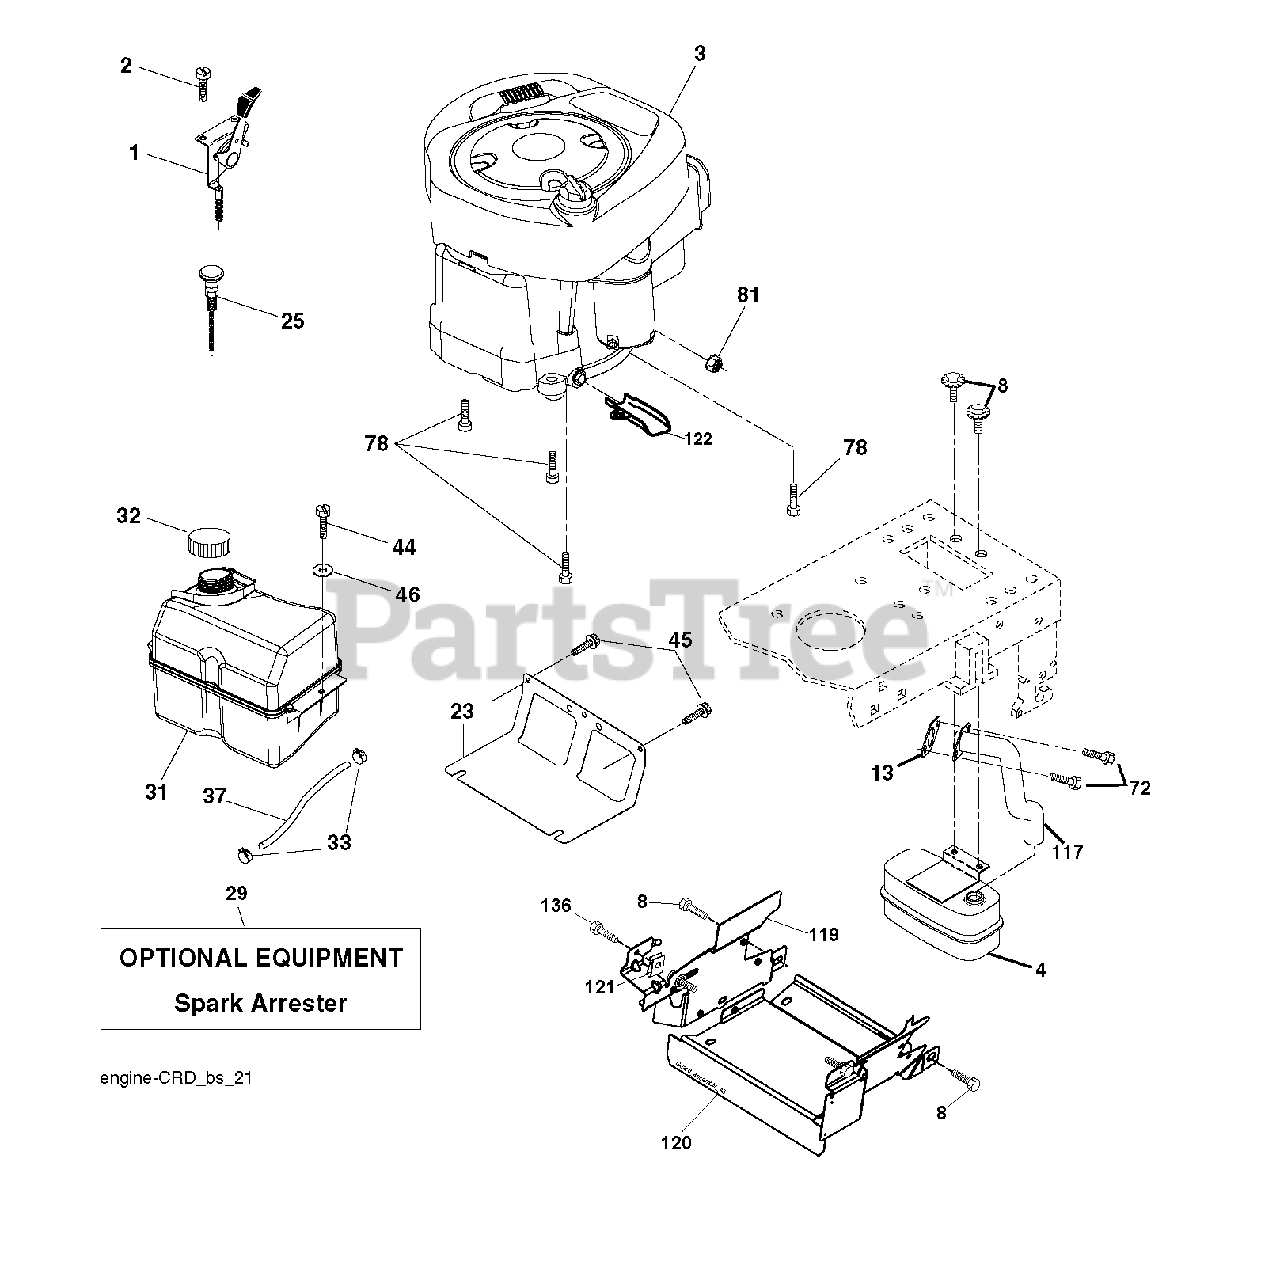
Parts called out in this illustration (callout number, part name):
1	CONTROL TH/CH FLAG
2	SCREW
4	MUFFLER.SINGLE.CYL.KOHL/B&S
8	BOLT, 5/16-18 X 1 3/4
13	REPL BY 532 27 22-93
23	SHEILD.BROWNING.DBR.GUARD
29	ARRESTER SPARK (OPTIONAL)
32	CAP ASM.FUEL.2.25"FR.
33	HOSE CLAMP
37	LINE.FUEL.20
44	SCREW HEXWSHR 1/4-20X3/4
45	SCREW, 3/8-16X3/4
72	SCREW.SOCKET HD.5/16-1
78	SCREW.3/8-16
81	NUT
117	EXHAUST.TUBE.B&S.
122	EXTENSION DRAIN OIL
136	SCREW.1/4-20X5/8
